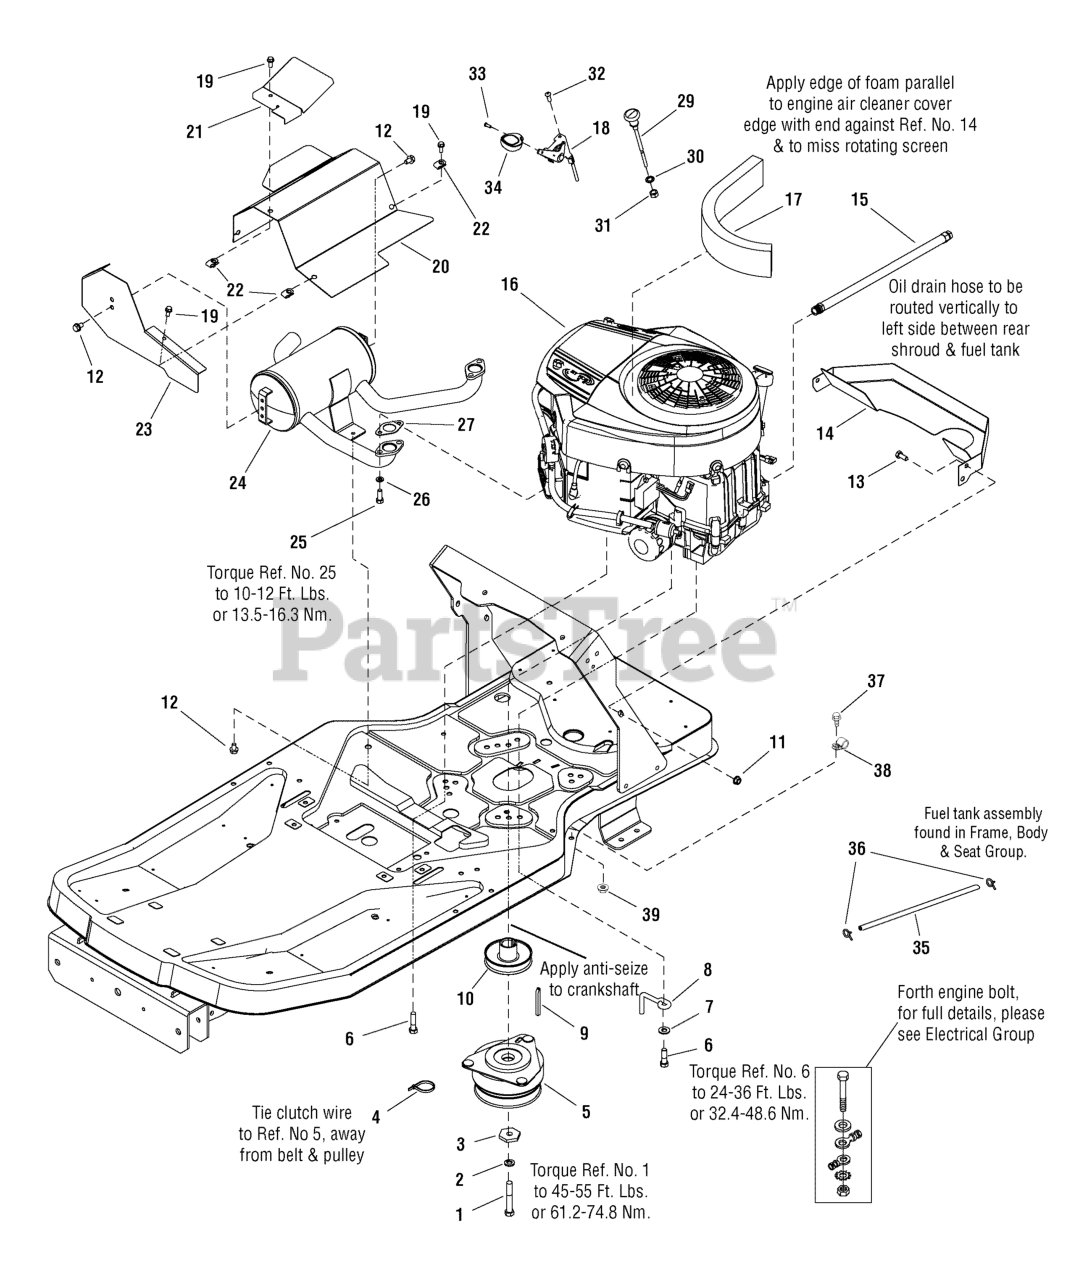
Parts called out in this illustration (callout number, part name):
1	CAPSCREW, Hex Head, 7/16-20 x 2-3/4, G5
2	LOCKWASHER, Spring
3	WASHER, Hex, 7/16
4	TIE, Self-Locking, 3.62"
5	CLUTCH, Electric Ogura
6	SCREW, Hex Washer Head Taptite, 3/8-16 x 1-1/4
7	WASHER, 3/8
8	RETAINER, Clutch
10	PULLEY ASSEMBLY, Engine
11	NUT, Hex Whiz Lock Flange, 5/16-18
12	SCREW, Hex Washer Head Taptite, 5/16-18 x 1/2
13	CAPSCREW, Hex Head, 5/16-18 x 3/4, G5
14	AIR DUCT, Inlet
15	HOSE, Oil Drain, 16.5"
16	ENGINE, 24HP Briggs & Stratton
17	SEAL, Foam Air Inlet
18	THROTTLE ASSEMBLY
19	SCREW, Hex Whiz Lock Flange, 1/4-20 x 5/8
20	HEAT SHIELD, Muffler Top
21	HEAT SHIELD, Throttle
22	NUT, Speed, 1/4-20
23	HEAT SHIELD, Muffler Side
24	MUFFLER, 24HP V-Twin ELS
25	CAPSCREW, Hex Head, 5/16-18 x 3/4, G8
26	LOCKWASHER, Spring, 5/16
27	GASKET, Exhaust
29	CABLE, Choke
30	WASHER, Lock Internal Tooth, 3/8
31	NUT, Hex, 3/8
32	SCREW, Taptite Pan Head Torx, 1/4-20 x 5/8
33	SCREW, Taptite Pan Head Combo, #10-16 x 3/4
34	KNOB, Throttle
35	HOSE, Fuel, 19.5"
36	CLAMP, Hose
37	CAPSCREW, Hex Head 5/16-18 x 3/4
38	CLIP, Harness
39	NUT, Hex Whiz Lock Flange, 5/16-18
